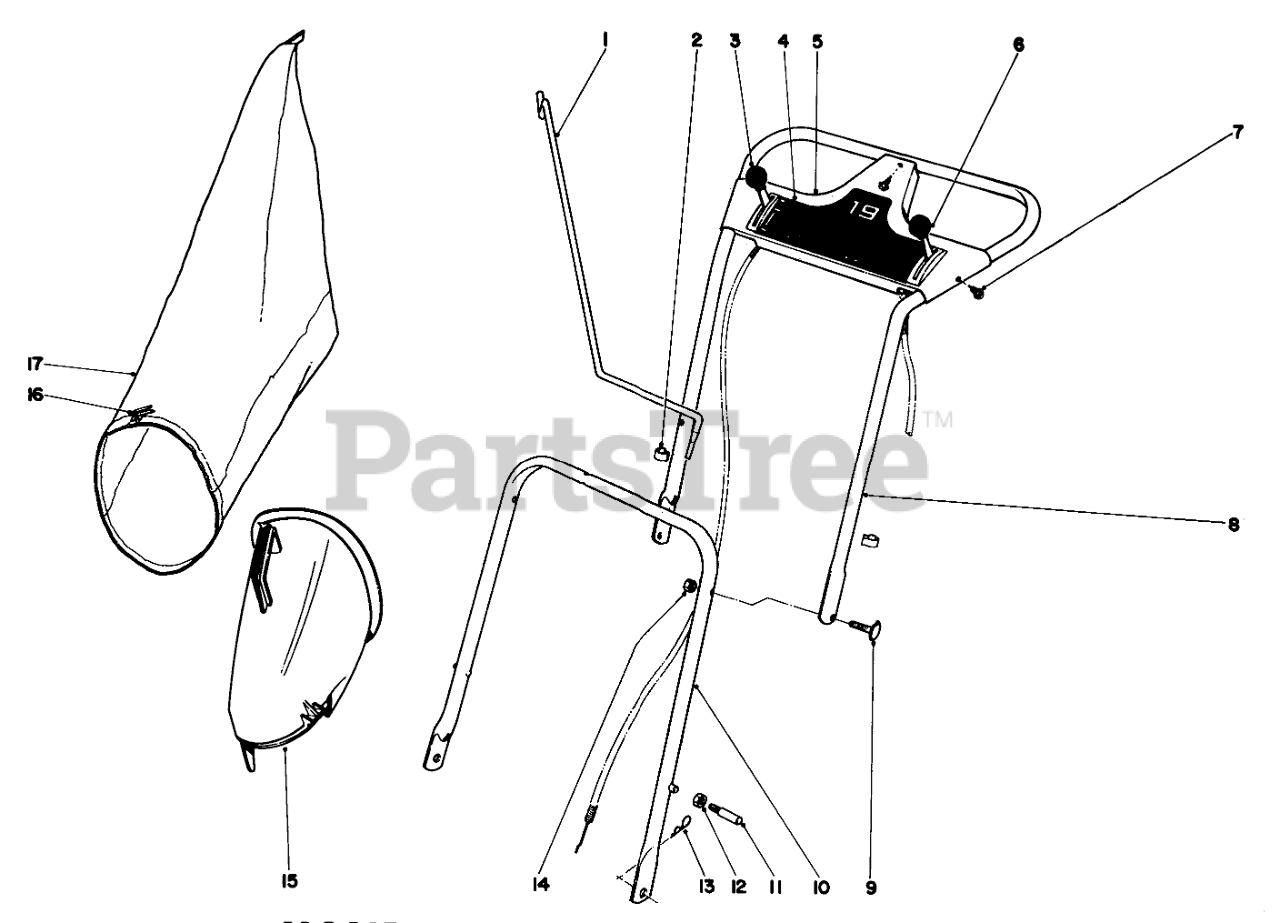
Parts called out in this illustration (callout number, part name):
1	Bag Hanger Rod
2	CONTROL WIRE CLIP
3	Throttle Control
4	Decal, Escutcheon Plate
5	Escutcheon Plate
6	Traction Control
7	SCREW-HWHTF
8	Upper Handle
9	1-1/4 LG HANDLE SCREW
10	Lower Handle
11	Handle Pin
12	Nut
13	PIN-COTTER, HAIR
14	Nut
15	Bag Attachment
16	BAG CORD FASTENER
17	Grass Bag Kit
